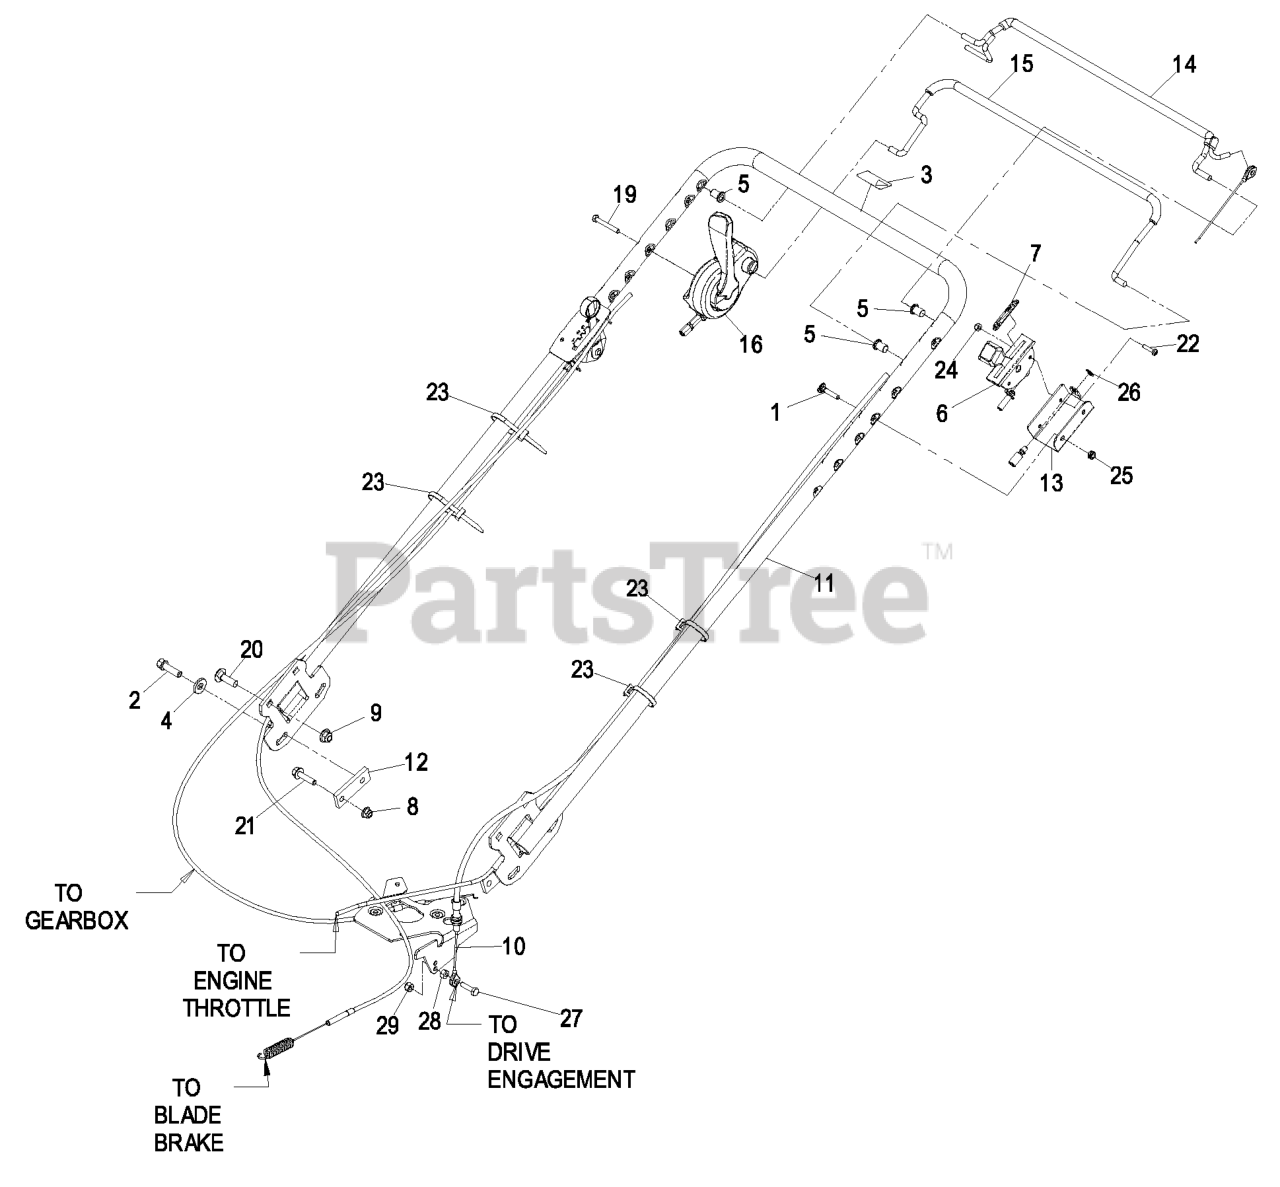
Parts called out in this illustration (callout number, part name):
1	BOLT-HANDLE
2	SCREW-TAPTITE
3	DECAL-PROTECTION, EAR
4	WASHER-BELLEVILLE
5	BUSHING
6	CONTROL-THROTTLE
7	DECAL-THROTTLE / CHOKE
8	NUT-HF, NI
9	NUT-HF, NI
10	CABLE-TRACTION
11	ASM,HANDLE W/DECALS
12	NUT-HANDLE
13	BRACKET-CONTROL
14	BAIL-TRACTION
15	BAIL-BBC (WITH GRIP)
16	CONTROL-BBC
17	CONTROL-SHIFT
18	SCREW-HH
19	SCREW-HH
20	BOLT-CARR
21	SCREW-HHF
22	SCREW-PPH
23	TIE-CABLE
24	NUT-LOCK, NI
25	NUT-LOCK, NI
27	SCREW-HH
28	NUT-HEX
29	NUT-LOCK, NI
32	CABLE-SHIFTER
